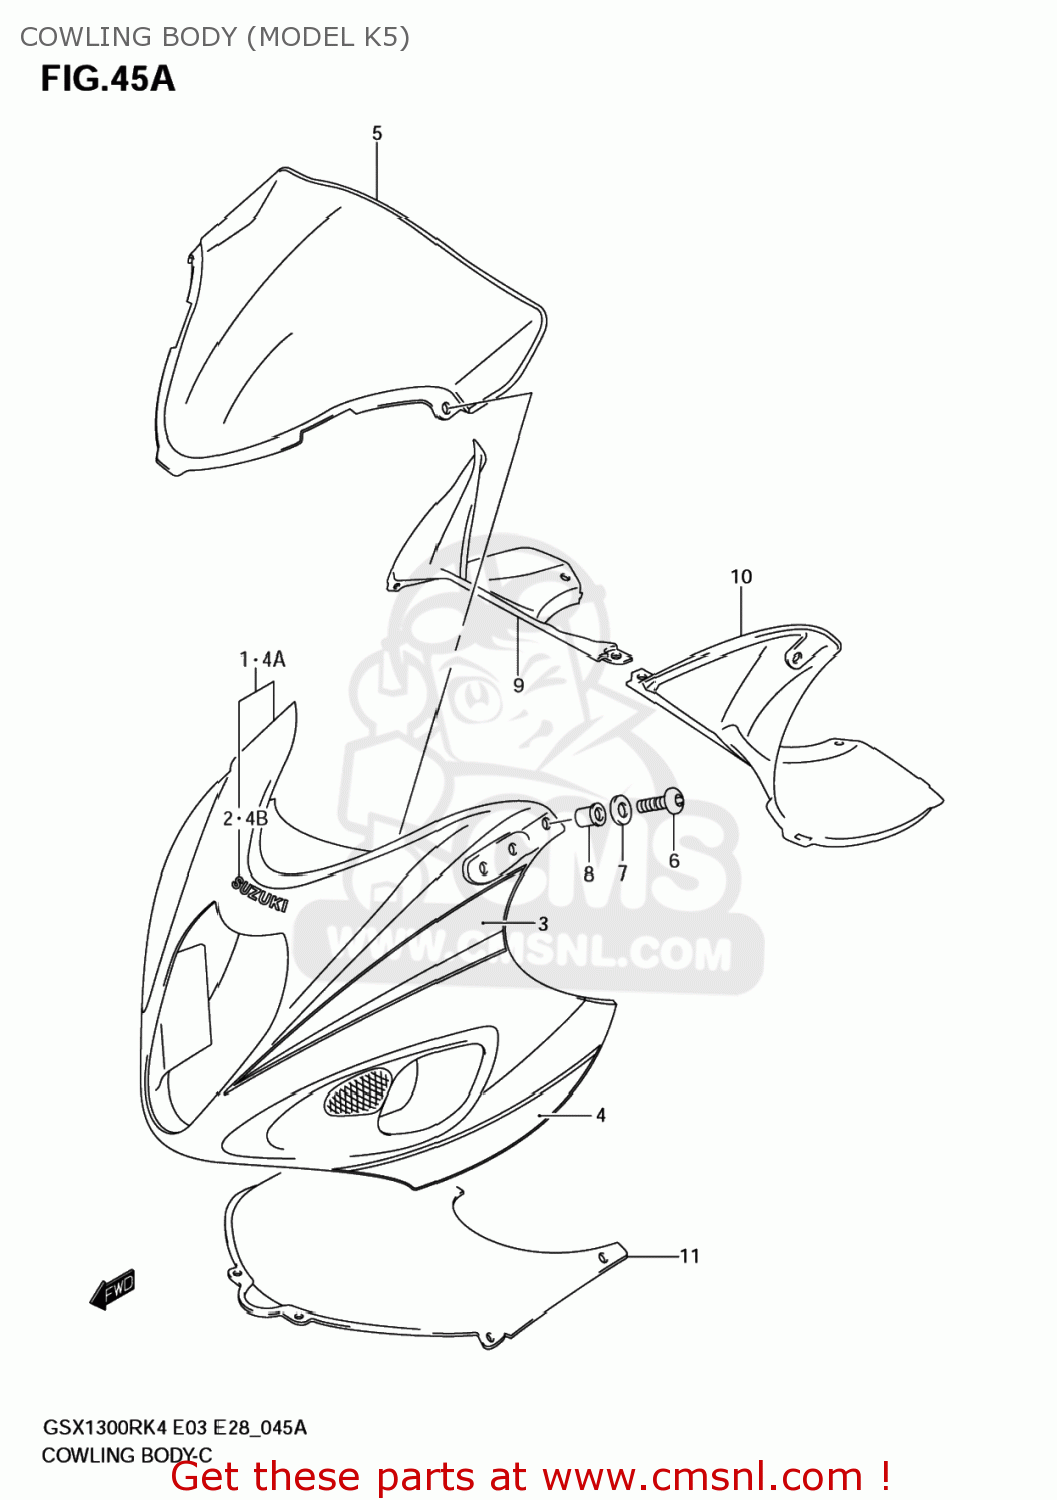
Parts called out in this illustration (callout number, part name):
1	COWLING ASSY,BODY
2	EMBLEM
3	TAPE SET,COWL BODY UPR
4	TAPE SET,COWL BODY SIDE
4A	COWLING ASSY,BODY
4B	EMBLEM,SUZUKI
5	WINDSCREEN
6	SCREW(5X14)
7	WASHER
8	NUT
9	PANEL,UPR,R
10	PANEL,UPR,L
11	COVER,BODY COWLING
